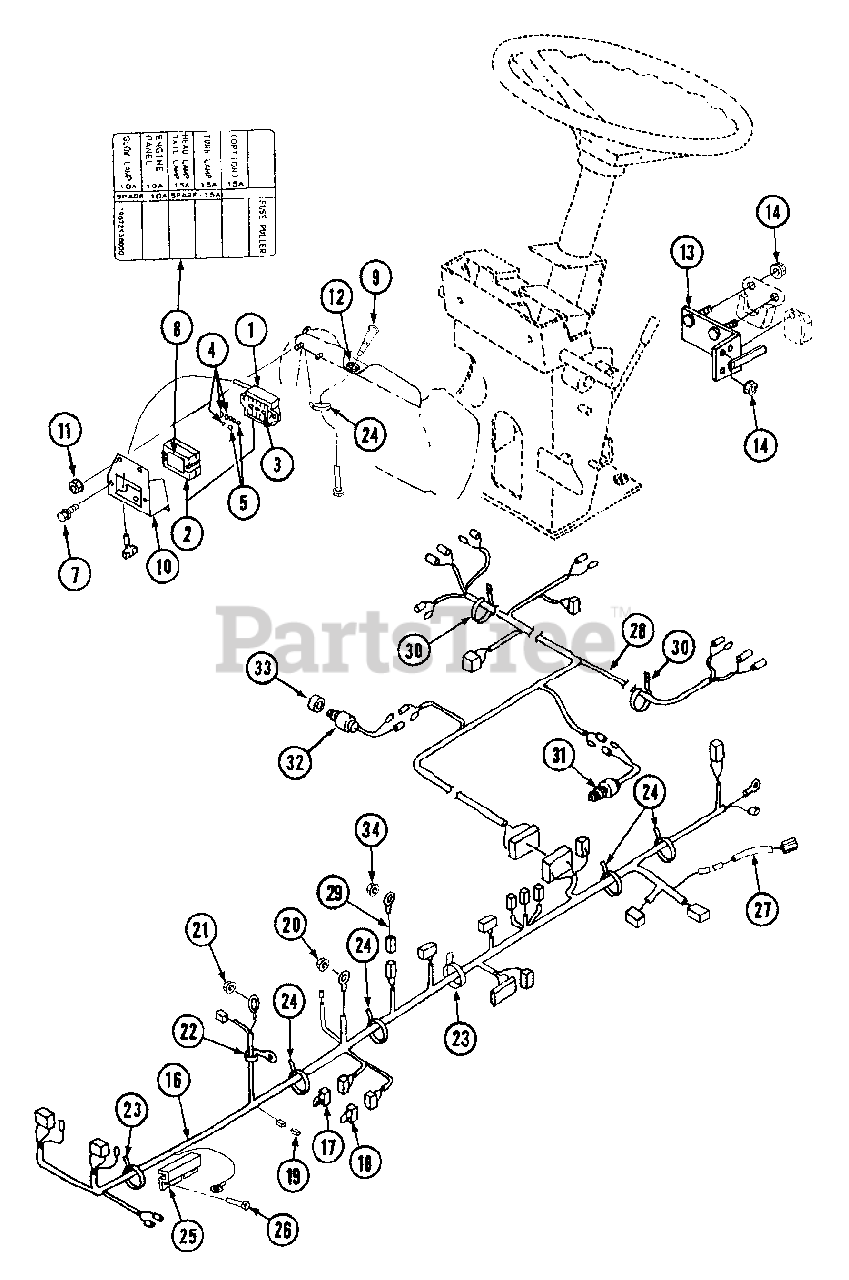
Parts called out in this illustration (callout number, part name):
1	Body Assy.
9	Cable, Flexible
16	Harness
27	Wire Lead
31	Switch, Safety
